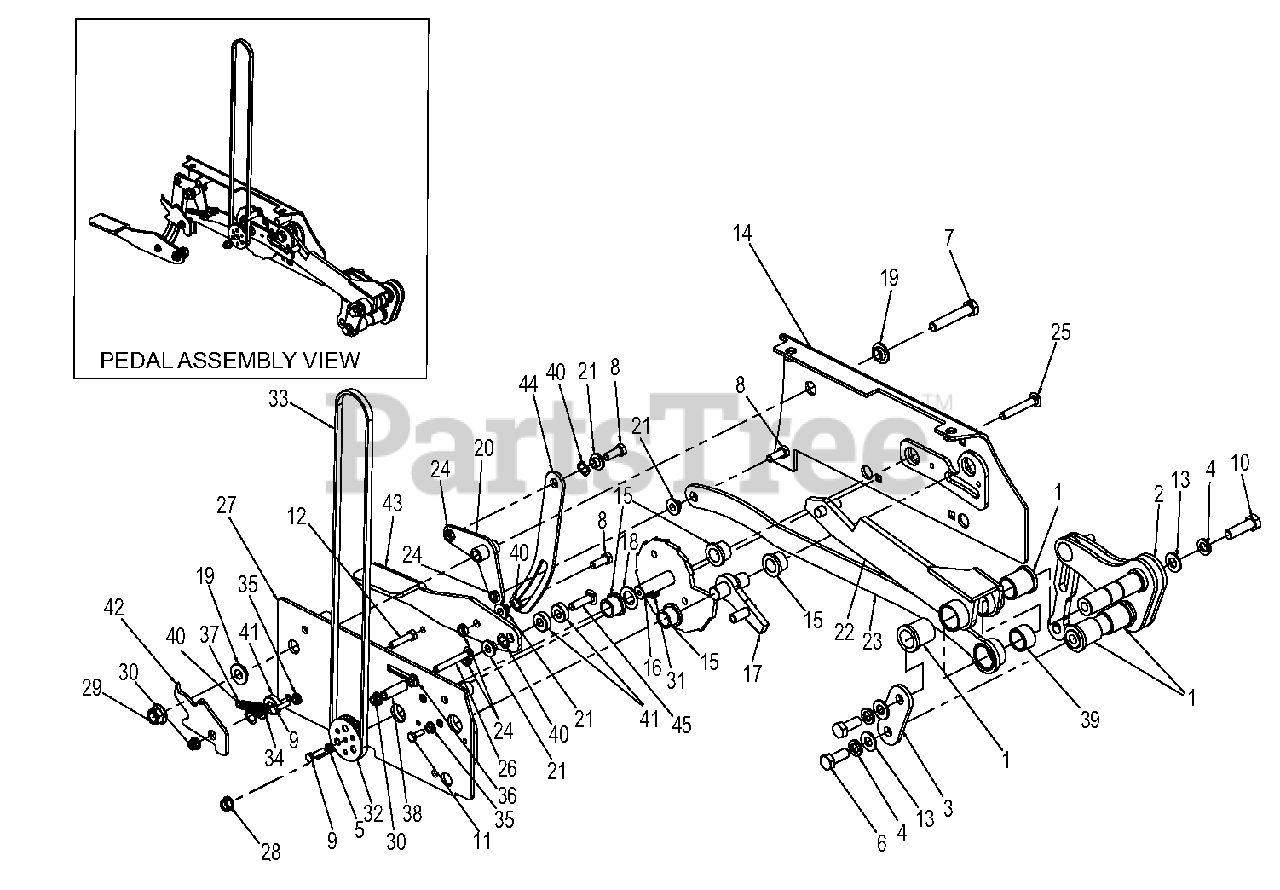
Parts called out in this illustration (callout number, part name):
1	BSHG-FLG 1.00 X 1.25 X 1.5 X 1.5
2	WLDMT, DECK ARM
3	PLATE, LIFT LINK ATTACH
4	WSHR-LK .50X .125 REG YWZC
5	WSHR-LK .25 X .062 REG YWZC
6	BLT-HEX .50-13 X 1.25 GR5 YWZC
7	BLT-HEX .50-13 X 2.75 GR5 YWZC
8	BLT-HEX .38-16 X 1.00 GR5 YWZC
9	BLT-HEX .25-20 X 1.00 GR5 YWZC
10	BLT-HEX .50-13 X 1.75 GR5 YWZC
11	BLT-HEX .25-20 X .75 GR5 YWZC
12	BLT-HEX .31-18 X 1.50 GR5 YWZC
13	WSHR-FL-STL .531 X 1.06 X .095 YWZC
14	WLDMT, LH BOTTOM TOWER SIDE
15	BUSHING, .750 X 1.00 X .750
16	WLDMT, HEIGHT OF CUT
17	WLDMT, TRAILER LOCK
18	BUSHING, MACH .75 X 1.25 X .048
19	BSHG, FLANGE .515 X .750 X .31 X 1.12
20	WLDMT, REAR PIVOT
21	BSHG, FLG .385 X .500 X .875 X .406
22	WLDMT, CAM CONTACT
23	WLDMT, DECK LIFT LINK
24	NUT-LK-CTR-JAM .375-16 YWZC
25	BLT-RDHDSQNK .38-16 X 2.50 G5 Y
26	BLT-RDHDSQNK .31-18 X 2.50 G5 Y
27	WLDMT, CAM COVER
28	NUT, LK-TOP-FLG .38-16 YWZC
29	NUT-LK-NYL-FLG .50-13 YWZC
30	NUT-LK-NYL-FLG .31-18 YWZC
31	KEY, .125 SQ. X .50
32	WLDMT, PULLEY
33	BELT, TIMING-LONG
34	BSHG-FLG .312 X .500 X .344
35	NUT=SPNLK=FLG .25-20 YWZC
36	NUT-SPNLK-FLG .312-18 YWZC
37	SPRG, EXTENSION
38	BSHG, SLV .33 X .50 X 1.56
39	BSHG, 1.00 X 1.25 X .75
40	WAVE WASHER .531 X .781 X .125 FH
41	SPCR, .375 X 1.00 X.342
42	LATCH, FOOT PEDAL
43	ARM, LOWER TURN
44	ARM, PEDAL
45	BLT-RDHDSQNK .38-16 X 1.50 G5 Y
